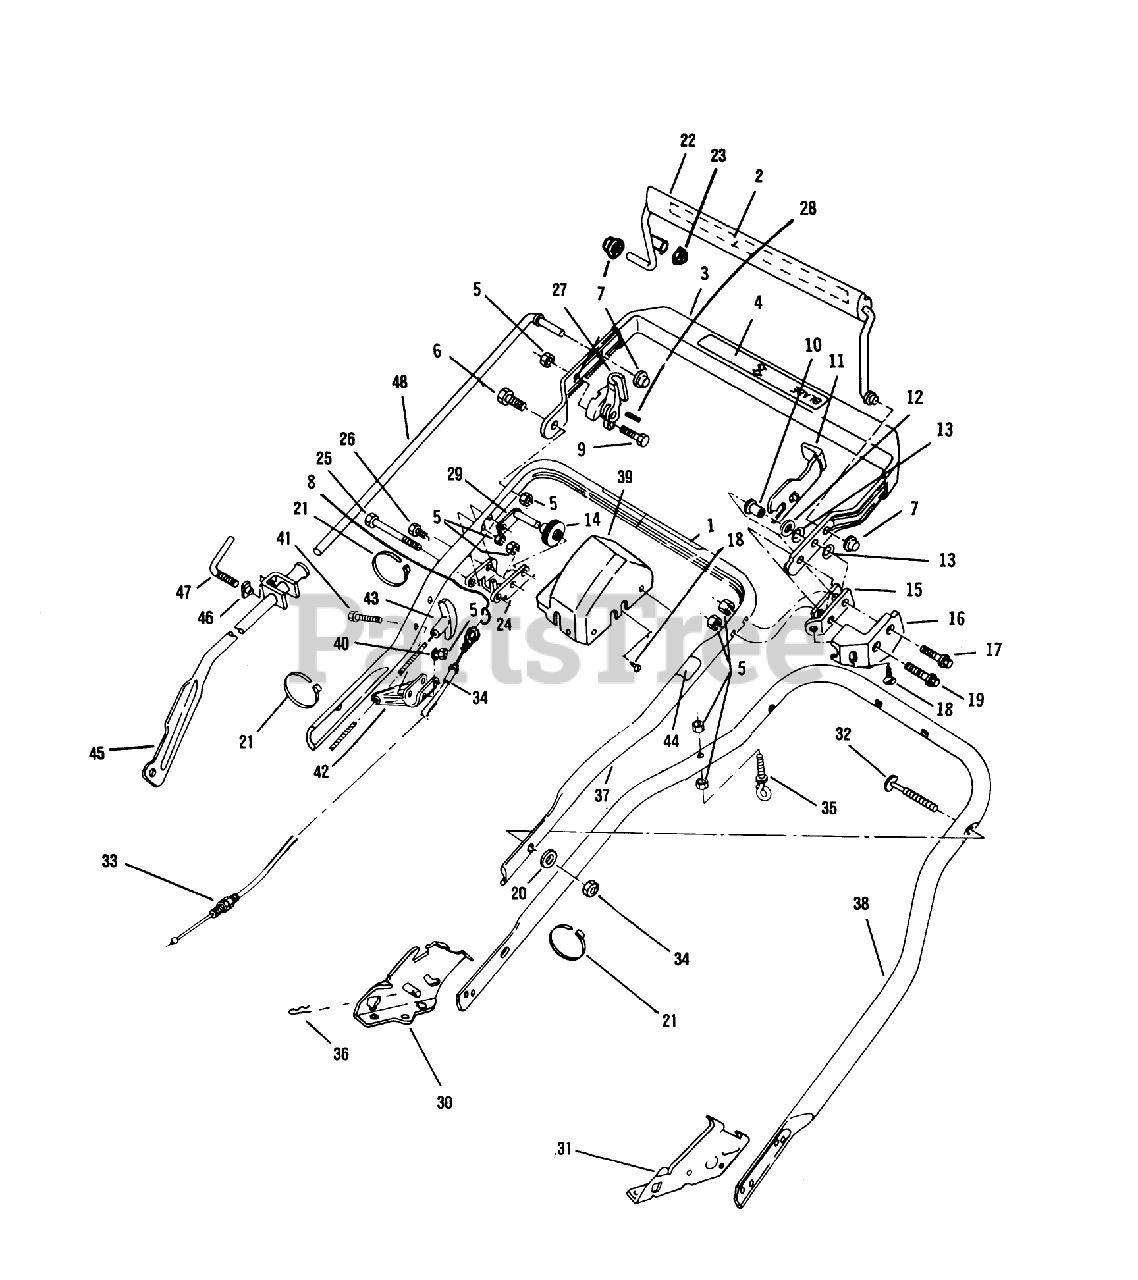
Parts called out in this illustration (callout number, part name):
5	LOCKNUT E
6	BOLT
8	RET. RING
10	SPACER
12	WASHER M
15	DOWN STOP
16	LOCKOUT GUARD
17	BOLT SHOU
18	SCREW F
19	SCREW
20	WASHER-CURVED
23	NUT ACORN
25	BOLT-CONSOLE
30	BRACKET ASM - HANDLE, SP, RH
31	BRACKET ASM - HANDLE, SP, LH
33	CONTROL CABLE
34	NUT-LOCK F
35	EYE BOLT WAS MFG
36	HAIR PIN
40	WASHER
43	HANDLE,STARTER
48	CONTROL ROD
